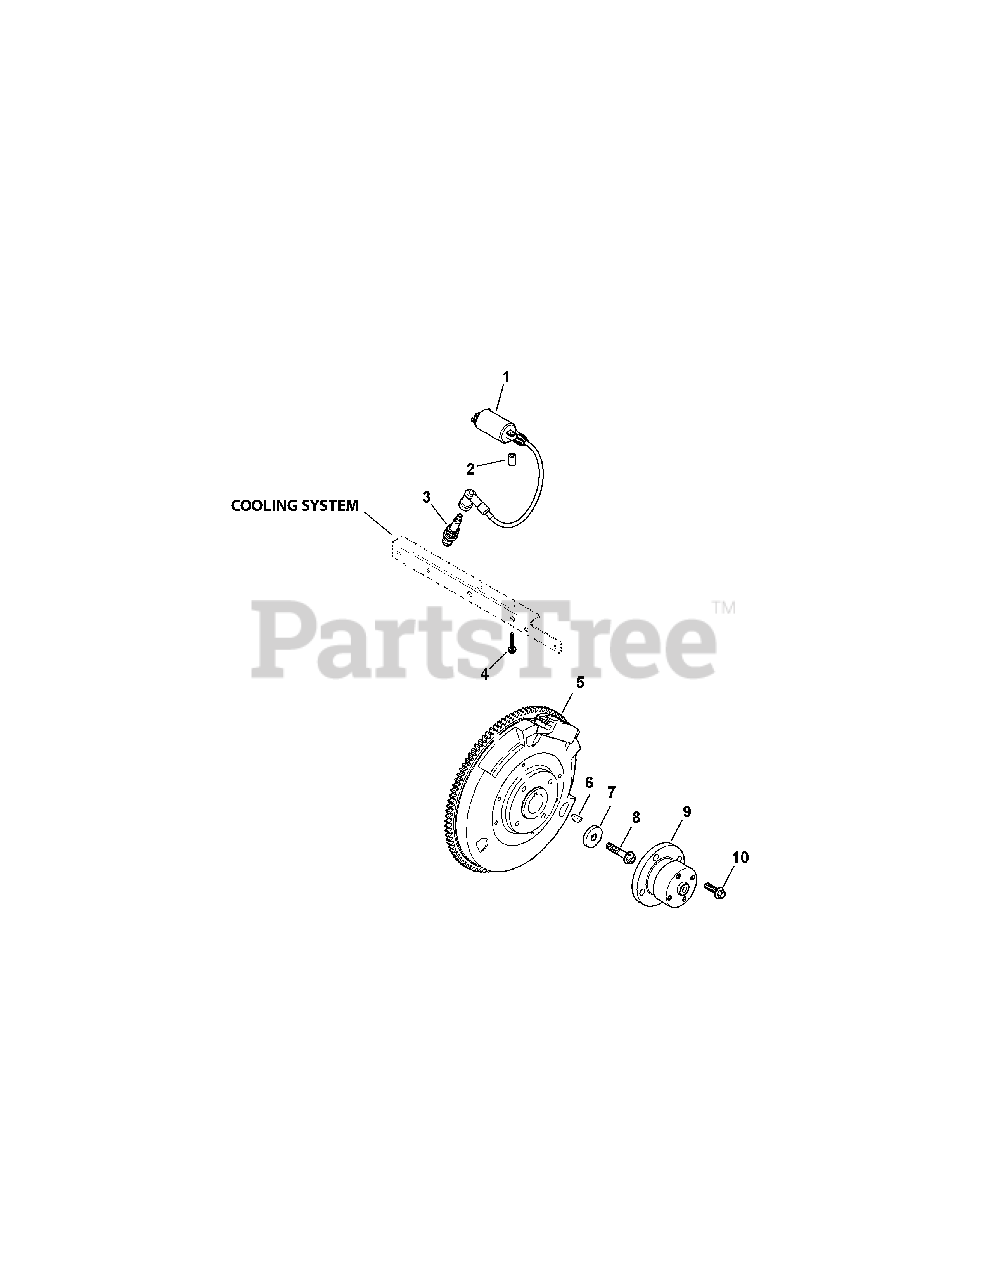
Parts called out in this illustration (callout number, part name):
1	Coil, Ignition
4	Screw, Thrd Frm, M6 x 1.0 x 45
5	Kit, Flywheel
6	Key, 3/16" x 5/8"
7	Washer, Flat, 13/32"
8	Screw, Flg, M10 x 1.5 x 45
9	Shaft, Front Drive
10	Screw, Flg, M8 x 1.25 x 25
